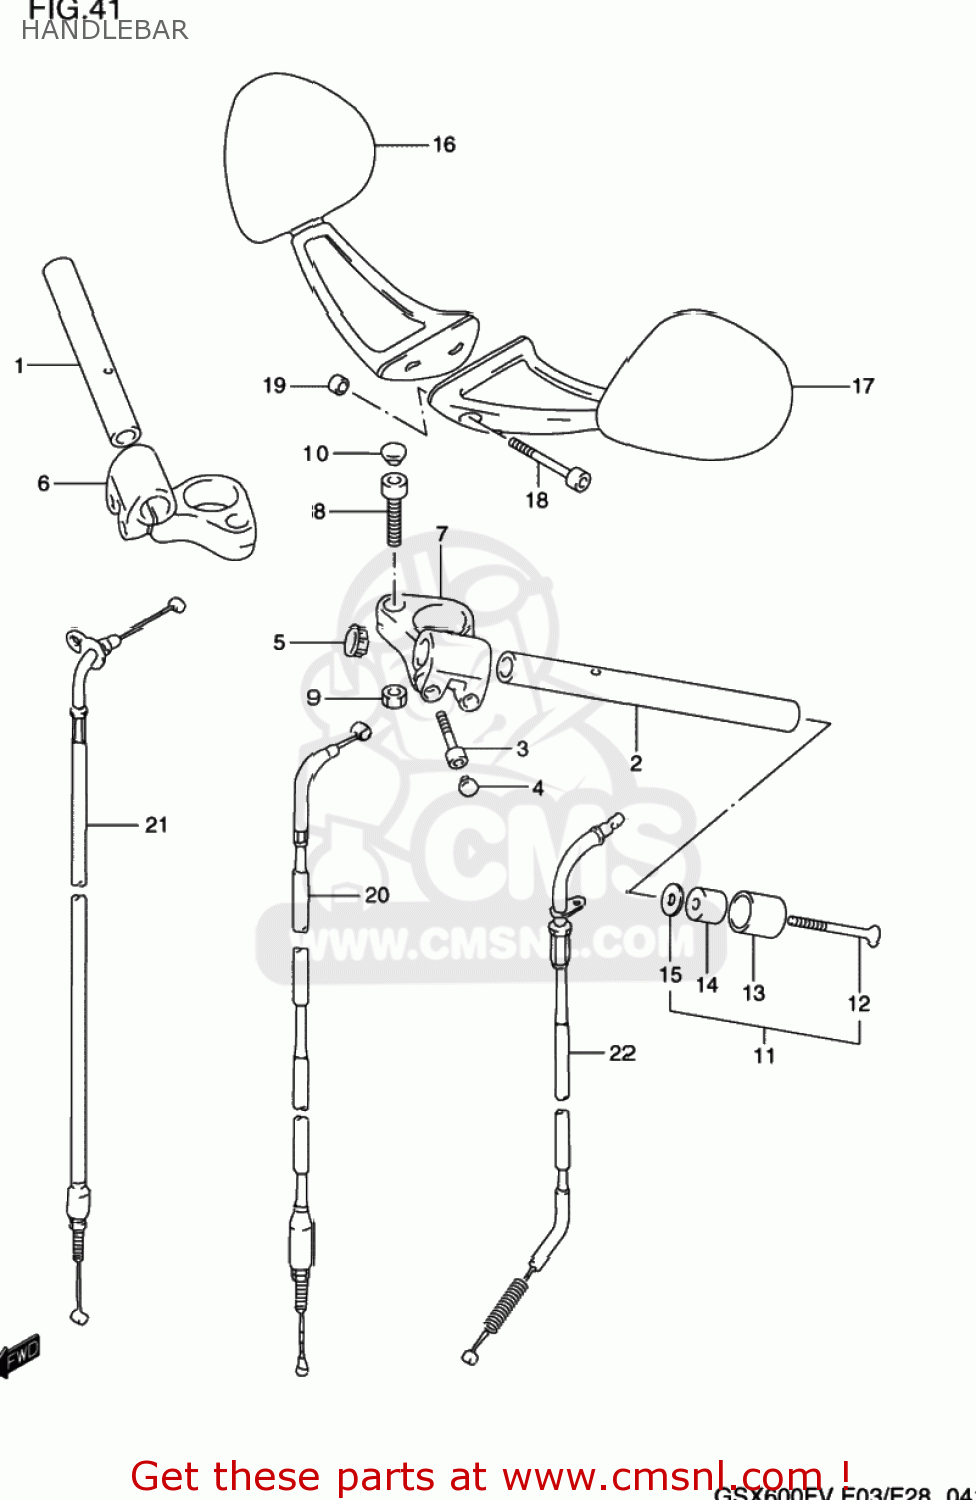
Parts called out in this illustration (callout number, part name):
1	HANDLEBAR,R
2	HANDLEBAR,L
3	BOLT
4	CAP(OD:10)
5	CAP,HANDLEBAR
6	HOLDER,HANDLE,RIGHT
7	HOLDER,HANDLE,LEFT
8	BOLT 10X45
9	NUT
10	CAP(OD:20)
11	BALANCER SET,HANDLEBAR
12	SCREW
13	CAP,BALANCER
14	BALANCER,HANDLE
15	SPACER,BALANCER
16	MIRROR ASSEMBLY,REAR VIEW
17	MIRROR ASSEMBLY,REAR VIEW
18	BOLT
19	SPACER(6.5X9X3.8)
20	CABLE ASSY,CLUTCH
21	CABLE ASSY,THROTTLE
22	CABLE,STARTER
